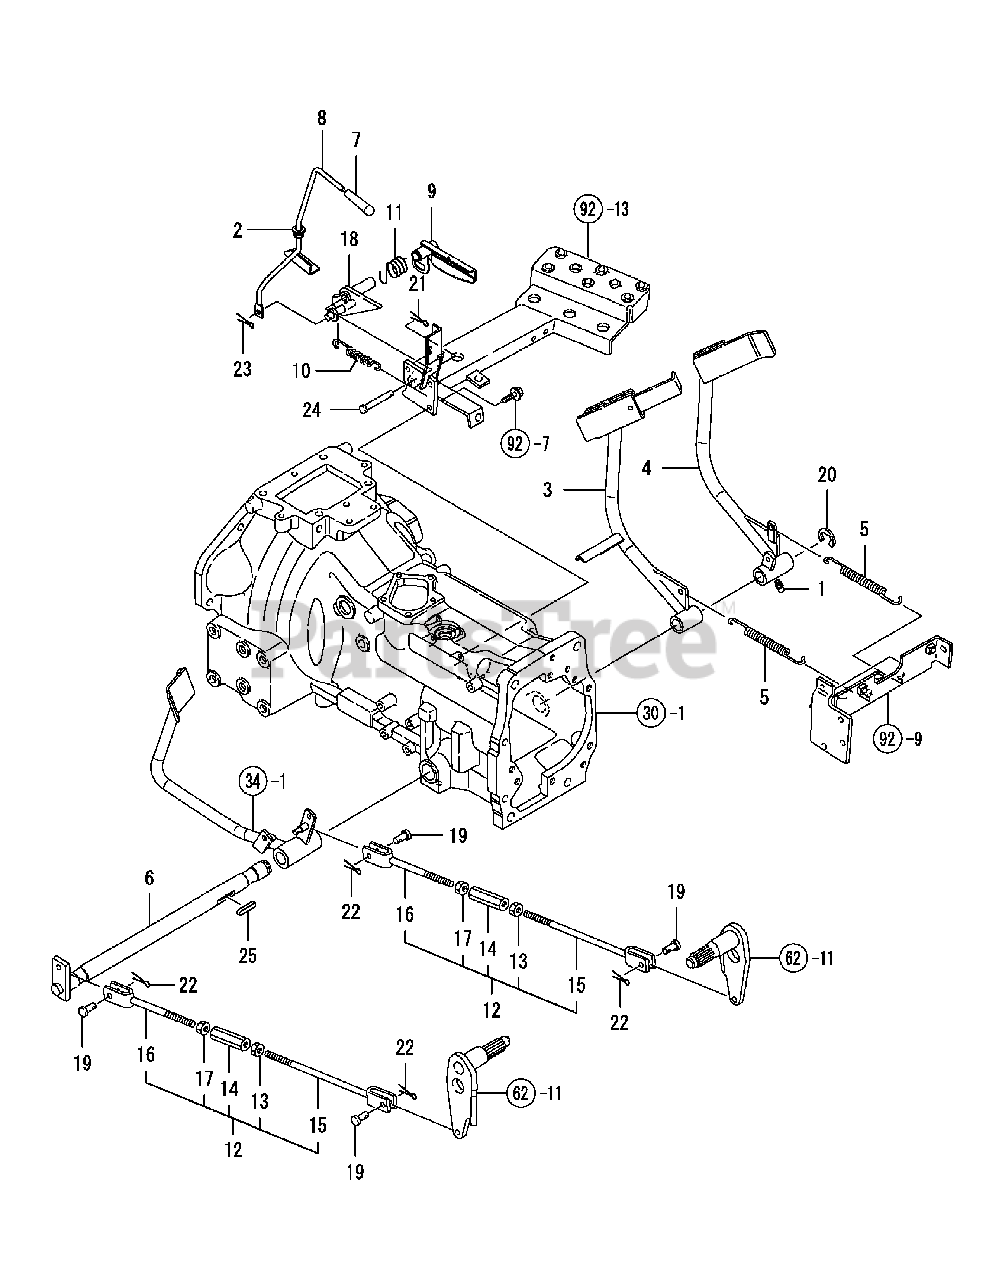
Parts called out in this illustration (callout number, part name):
1	NIPPLE M6F, GREASE
2	GUIDE,FRONT SHIFT
3	PEDAL L.H., BRAKE
4	PEDAL R.H., BRAKE
5	SPRING, RETURN
6	SHAFT, BRAKE PEDAL
8	ROD,PARKING CMP
9	LEVER,PARKING BRAKE
14	TURNBUCKLE M10X70
18	LEVER(B, PARKING
21	COTTER PIN 2.0X30
22	COTTER PIN 2.5X30
23	COTTER PIN 2.5X30
